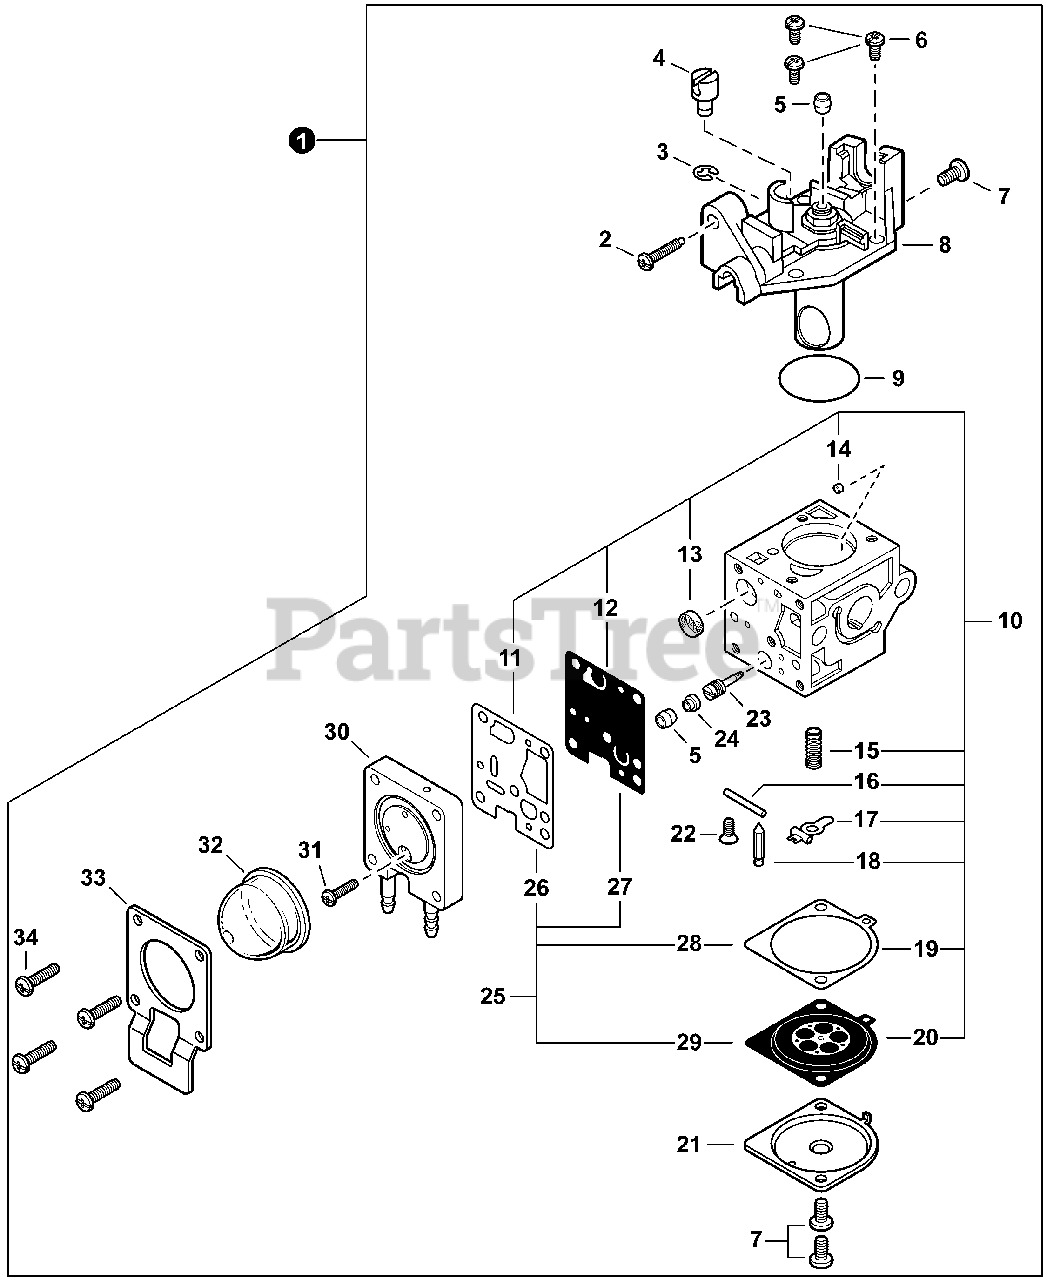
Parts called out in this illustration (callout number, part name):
1	CARBURETOR - Z011-67A
2	SCREW, IDLE ADJUST
8	COVER ASSY, ROTOR
10	REPAIR KIT, CARBURETOR
11	++GASKET, PUMP
12	++DIAPHRAGM, PUMP
13	++SCREEN, FUEL INLET
14	++GUIDE, ROLLER
15	++SPRING, METERING LEVER
16	++PIN, METERING LEVER
17	++LEVER, METERING
18	++VALVE, INLET NEEDLE
19	++GASKET, METERING DIAPHRAGM
20	++DIAPHRAGM, METERING
21	COVER, METERING DIAPHRAGM
23	NEEDLE, HIGH SPEED
24	CAP, LIMITER
25	GASKET / DIAPHRAGM KIT
26	++GASKET, PUMP
27	++DIAPHRAGM, PUMP
28	++GASKET, METERING DIAPHRAGM
29	++DIAPHRAGM, METERING
30	BODY ASSY, PURGE
32	BULB, PURGE
33	RETAINER, PURGE BULB
